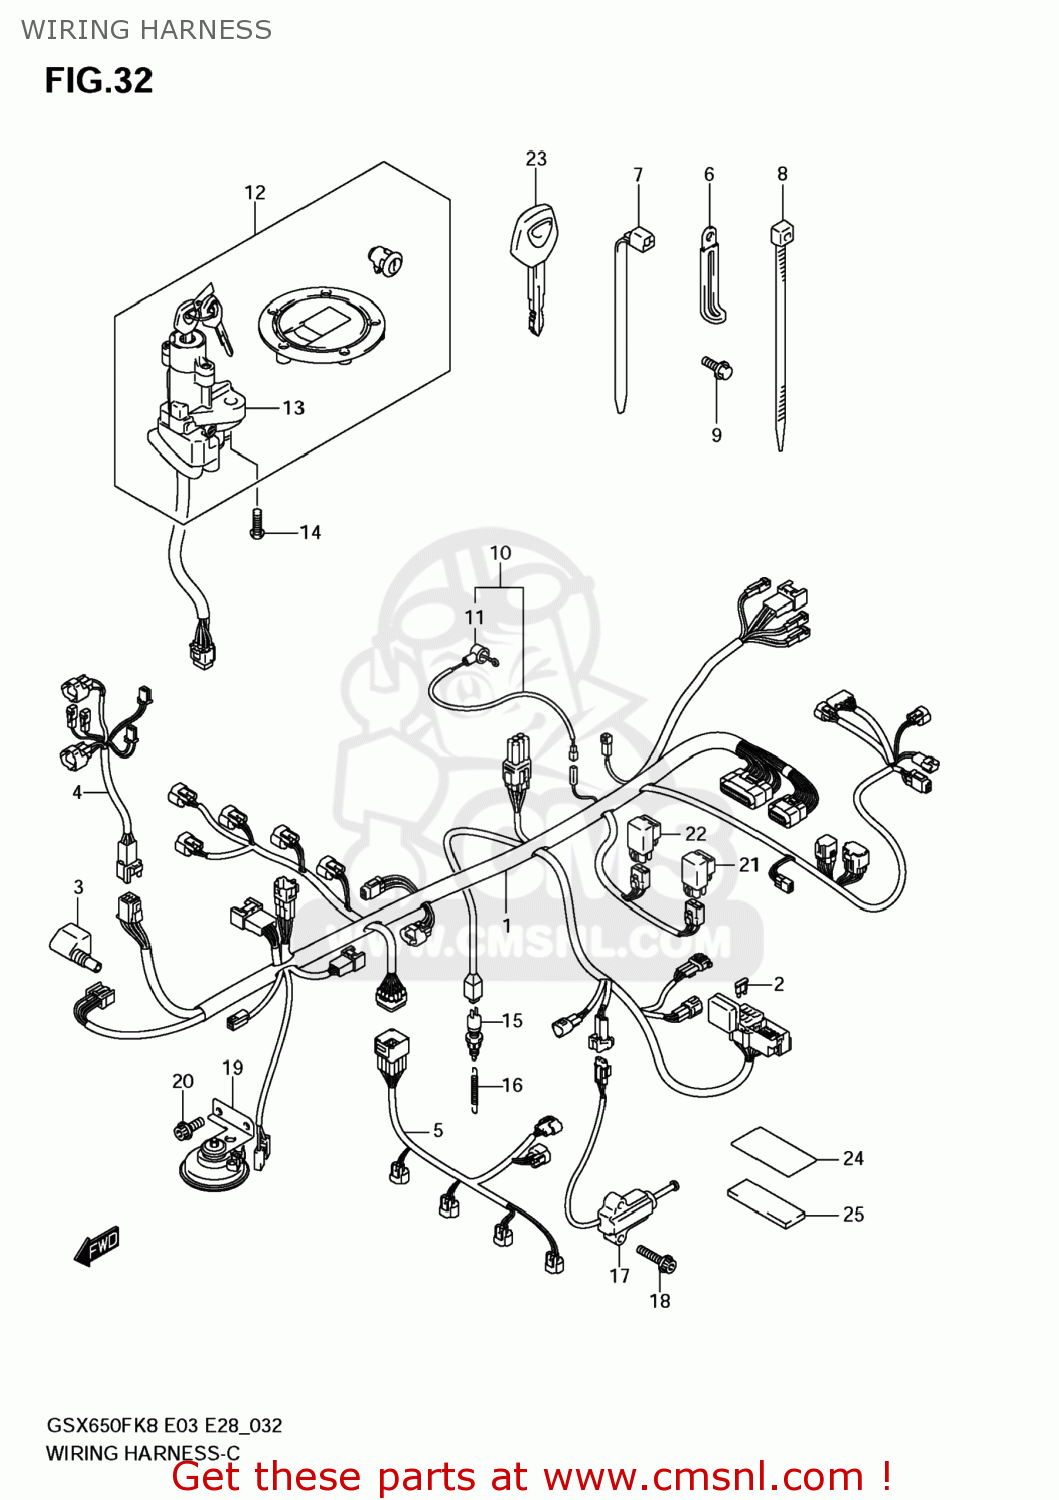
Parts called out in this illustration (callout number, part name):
1	HARNESS,WIRING NO.1
2	FUSE(10A)
3	COVER,SPEEDOMETER COUPLER
4	HARNESS,WIRING NO.2
5	WIRE,INJECTOR LEAD
6	CLAMP(L:45)
7	CLAMP(L:95)
8	CLAMP(L:145)
9	BOLT
10	WIRE,OIL PRESSURE SWITCH LEAD
11	CAP,OIL PRESSURE SWITCH
12	LOCK SET
13	LOCK ASSY,STEERING
14	BOLT(8X20)
15	SWITCH ASSY,STOP LAMP
16	SPRING
17	SWITCH ASSY,SIDE STAND
18	BOLT
19	HORN ASSY
20	BOLT
21	RELAY ASSY
22	RELAY ASSY
23	KEY,BLANK
24	TAPE,RR FENDER
25	PROTECTOR(20X90)X2
